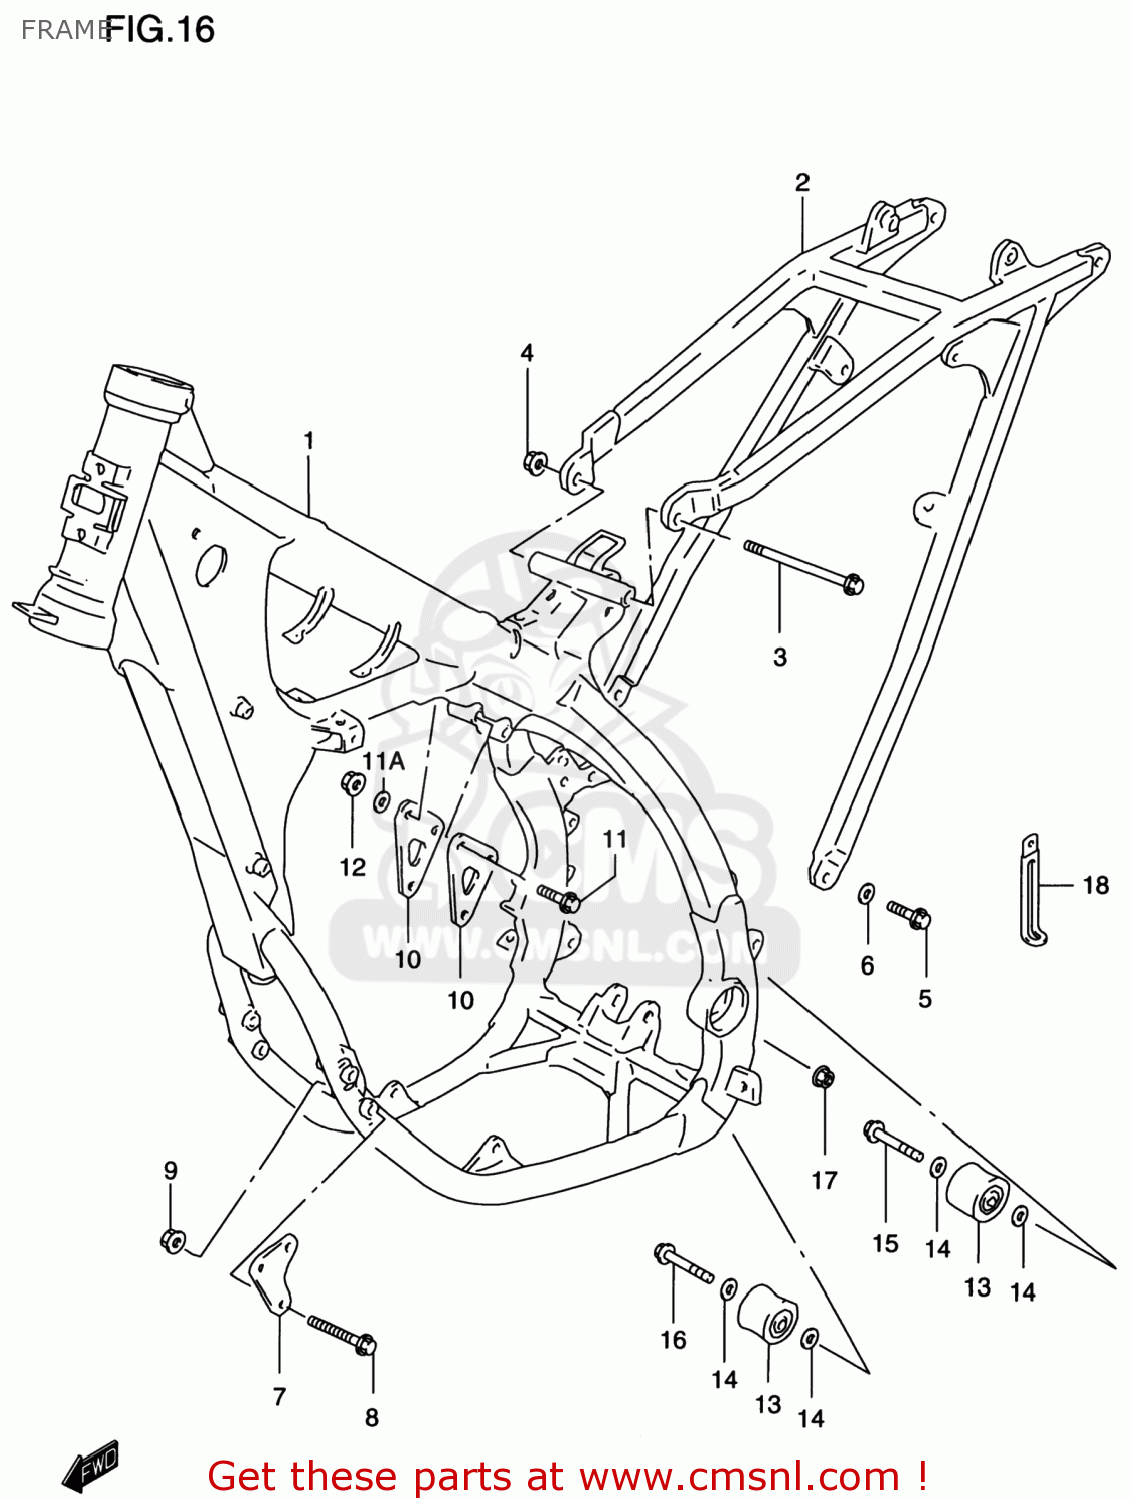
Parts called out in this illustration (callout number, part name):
1	FRAME(CHARCOAL)
2	RAIL,SEAT
3	BOLT(8X120)
4	NUT
5	BOLT 8X16
6	WASHER
7	PLATE,ENGINE MOUNTING
8	BOLT
9	NUT
10	PLATE,ENG MTG UPR
11	BOLT(8X45)
11A	WASHER
12	NUT
13	ROLLER,CHAIN
14	WASHER
15	BOLT(8X41)
16	BOLT(8X45)
17	NUT
18	CLAMP(L:65)
